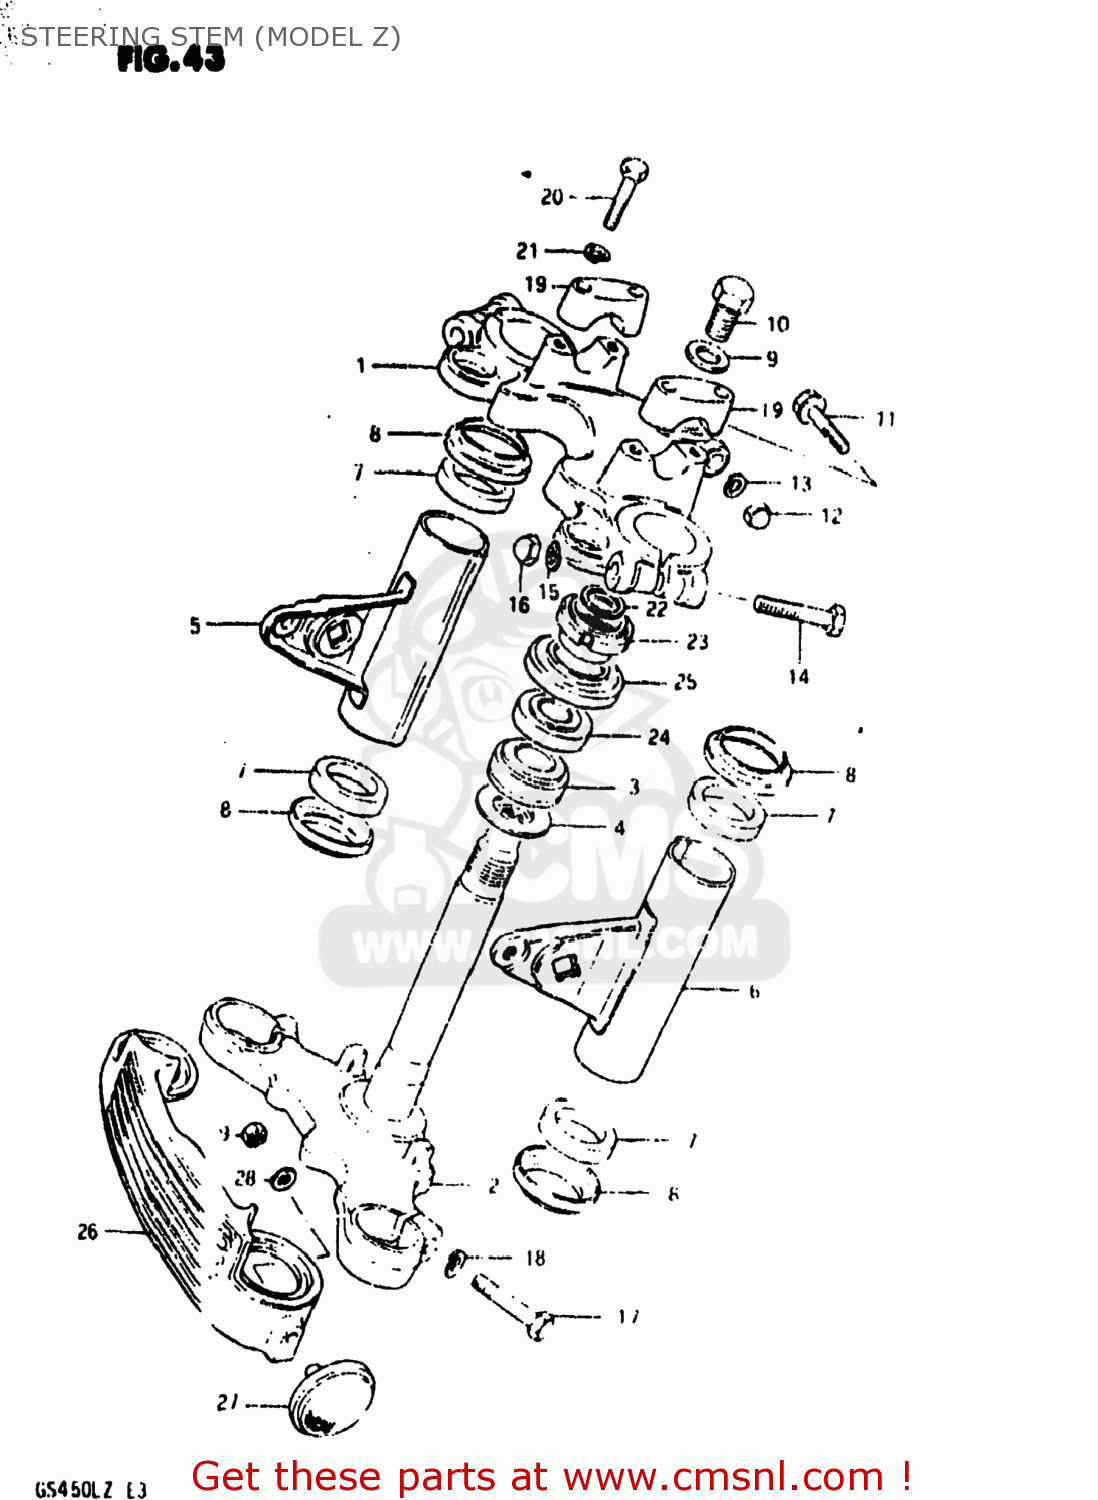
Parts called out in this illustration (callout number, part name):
1	HEAD,STEERING STEM
2	STEM,STEERING
3	BEARING
4	WASHER,THRUST
5	BRACKET,HEADLAMP,RIGHT
6	BRACKET,HEADLAMP,LEFT
7	CUSHION,HEADLAMP BRACKET
8	CAP,HEADLAMP BRACKET
9	WASHER
10	BOLT(12X20)
11	BOLT
12	NUT,M8X1.25X12
13	LOCK WASHER
14	BOLT 10X55
15	LOCK WASHER
16	NUT
17	BOLT 10X40
18	LOCK WASHER
19	HOLDER,HANDLE UPR
20	BOLT
21	LOCK WASHER
22	WASHER(18.5X24X1)
23	NUT,STEERING STEM
24	TAPER,ROLLER BEARING
25	DUST SEAL,STEERING UPR
26	COVER,FRONT FORK
27	REFLEX REFLECTOR,RR
28	WASHER
29	NUT
